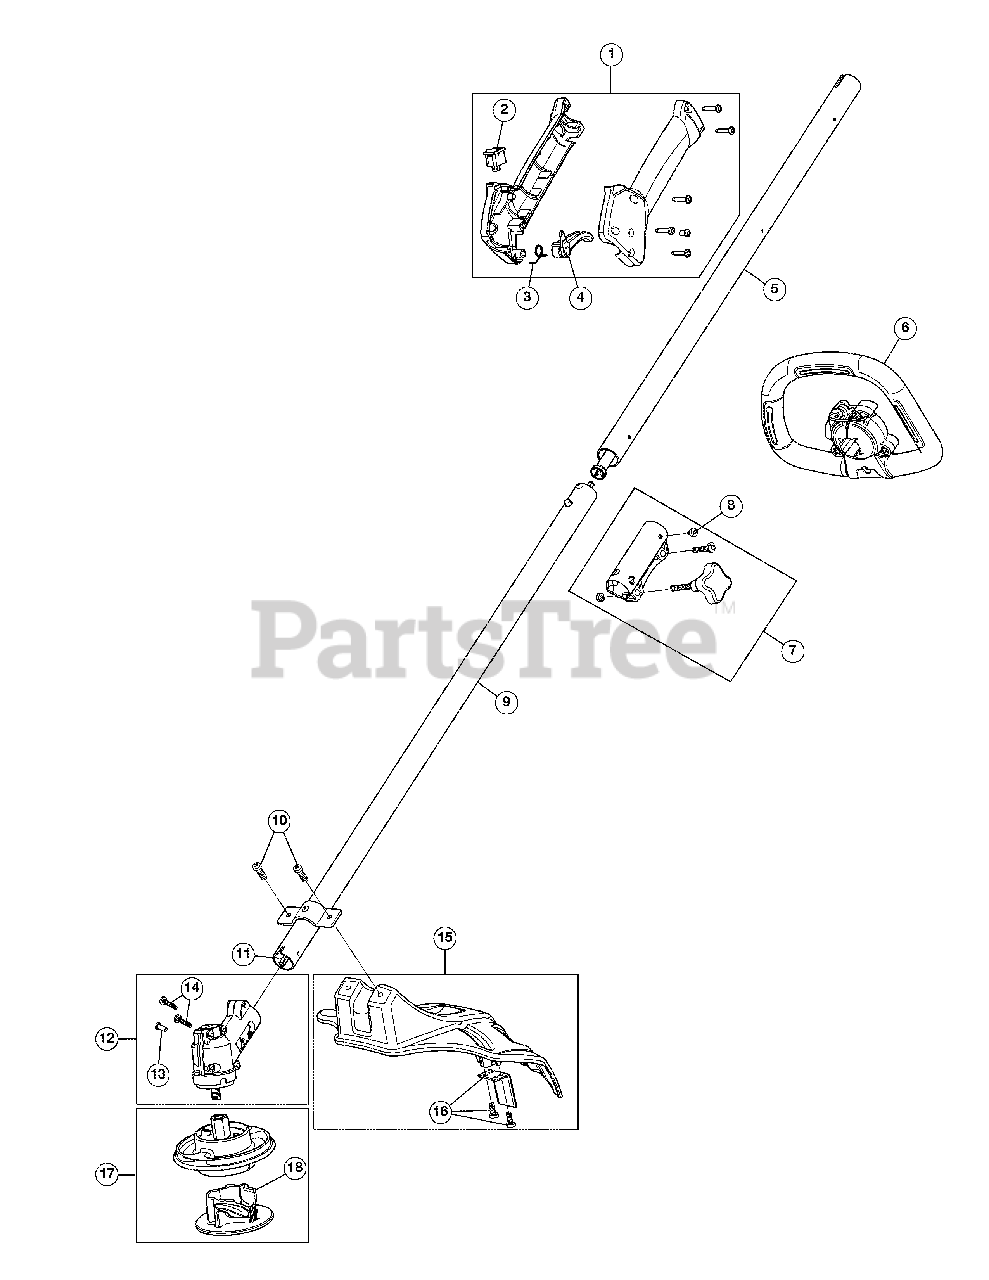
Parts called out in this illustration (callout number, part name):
1	Throttle Housing Assembly (Incl. 2 - 4)
2	Trigger Switch Assembly
3	Throttle Trigger Spring
4	Throttle Trigger
5	Upper Drive Shaft Assembly
6	Handle
7	Split Boom Coupler (Incl. 8)
8	Coupler Anti-Rotation Screw
9	Lower Drive Shaft Housing
10	Shield Mounting Screws
11	Lower Flexible Drive Shaft
12	Gearbox Assembly (Incl. 13 and 14)
13	Gearbox Anti-Rotation Screw
14	Gearbox Screw
15	Shield Assembly (Incl. 16)
16	Blade Assembly
17	Cutting Head Assembly (Incl. 18)
18	Cutting Head Cap
